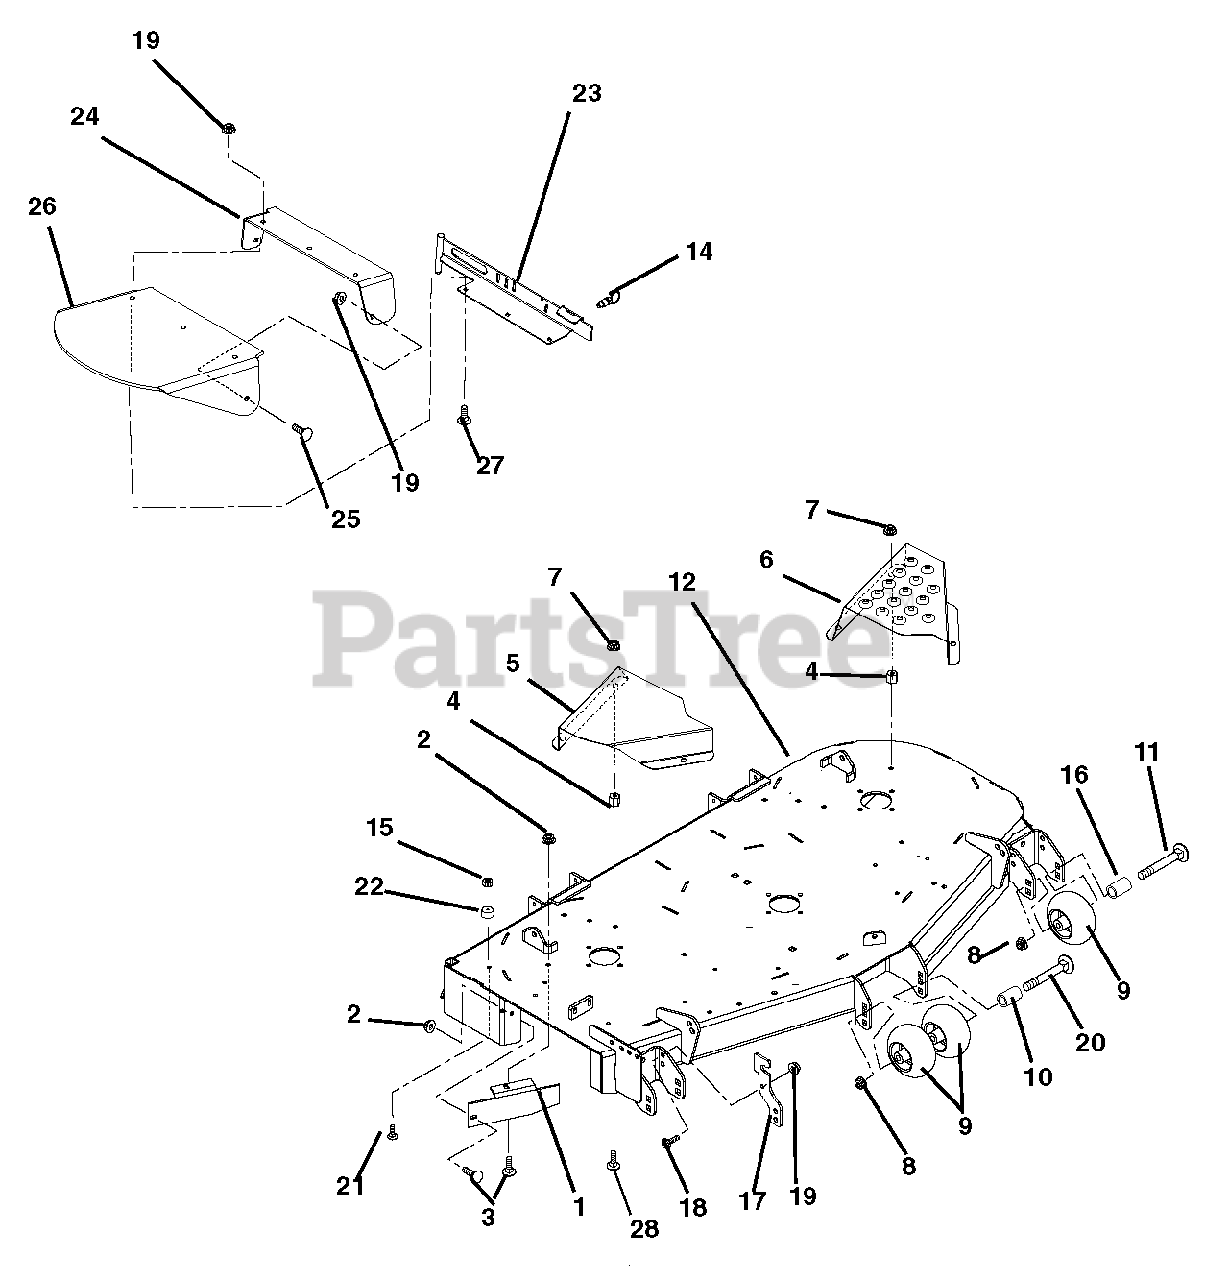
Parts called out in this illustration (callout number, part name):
1	60-in. Discharge Baffle
2	Nut, .31-18 Nyloc Flange
3	Bolt, Round Head Square Neck .31-18 x 1.00 Grade 5
4	Nut, Heavy Hex .38-16
5	60-in. Right Hand Spindle Guard
6	60-in. Left Hand Spindle Guard
7	Nut, Spin Lock-Flange .375-16
8	Nut .50-13 Nyloc Flange
9	Anti-Scalp Wheel
11	Bolt-Round Head Square Neck .50-13X5.00
12	60-in. Mower Deck
13	Knob, Clamping, .312-18 Nyloc
14	Pin, Plunger Pull .50-13 Thread x .310 Diameter
15	Nut, Locking, Center .31-18
16	Spacer, .510 x .625 x 3.35
17	Chute, Storage Bracket
18	Bolt, Hex .38-16 x 1.00 Grade 5
19	Nut, .38-16 Nyloc Flange
20	Bolt, Round Head Square Neck .50-13 x 8.50
21	Bolt, Round Head Square Neck .31-18 x 1.50
22	Bumper, Recessed 1.50 x .63 , .31 Thru Hole
23	52-inch and 60-inch Discharge Chute Mounting Weldment
24	Rubber Discharge Chute Support
25	Bolt, Round Head Square Neck .38-16 x 1.00 Grade 5
26	Chute, Rubber Discharge
27	Bolt, Round Head Square Neck .38-16 x 1.25 Grade 5
28	Bolt, Hex .38-16 x 1.25 Grade 5
